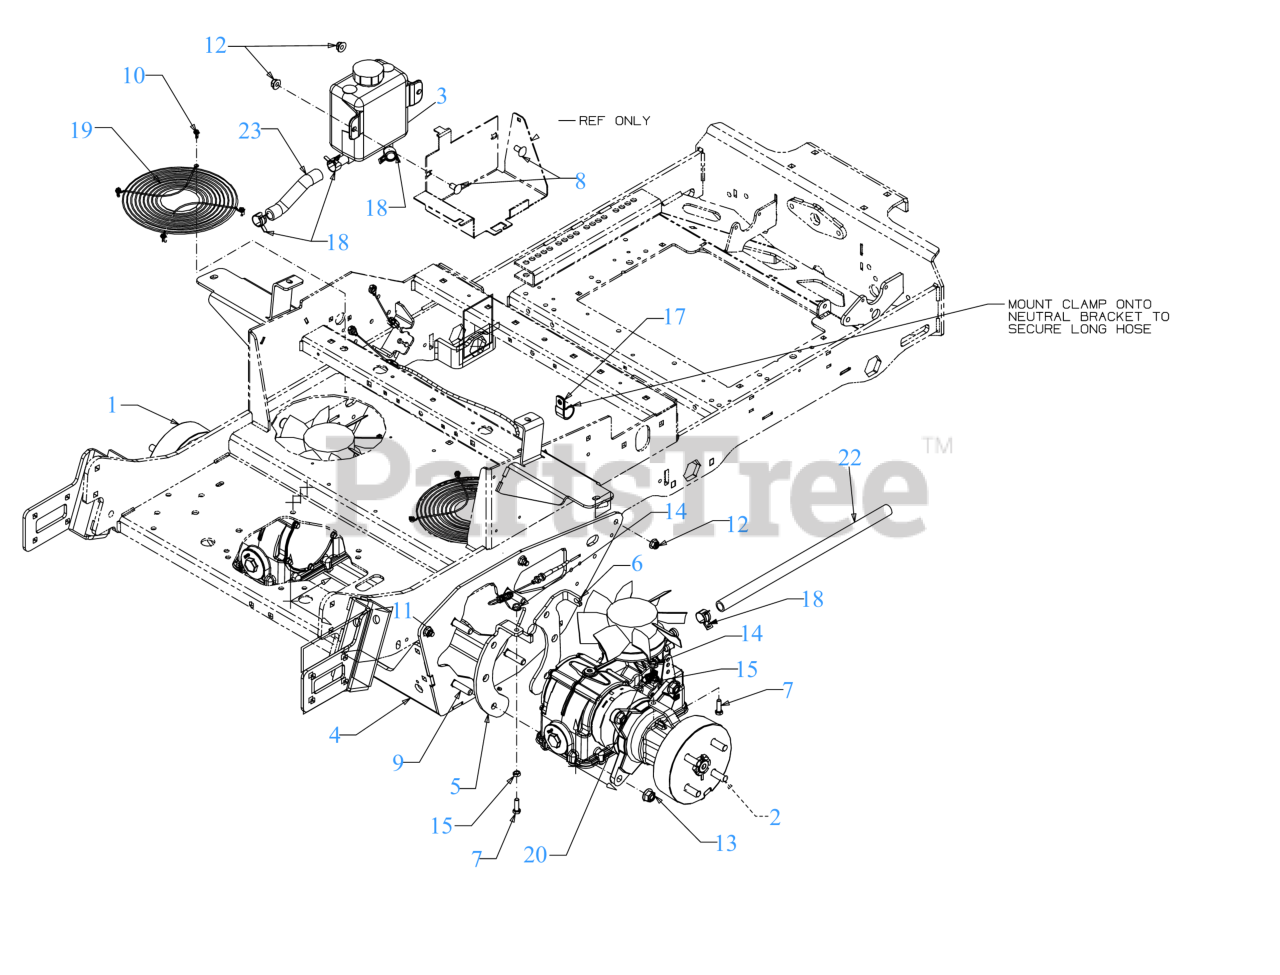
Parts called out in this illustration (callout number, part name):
1	TRANSMISSION ASSEMBLY PARKER (LH)
2	TRANSMISSION ASSEMBLY PARKER (RH)
3	HYDRO TANK ASSEMBLY
4	TRANSMISSION MOUNTING BRACKET
7	SCREW 5/16-18 x 1.0 GR5
8	CARRIAGE BOLT 3/8-16 x .750 GR5
9	CARRIAGE BOLT 1/2-13 GR5
10	SCREW 10-24 x 0.500
11	CARRIAGE BOLT 3/8-16 X1.25 GR5
14	HEX FLANGE NUT
17	HOSE CLAMP 1.0"
18	HOSE CLAMP
20	EXTENSION SPRING .500 OD x 1.71
22	OIL HOSE 5/8 ID x 18.00 LG
